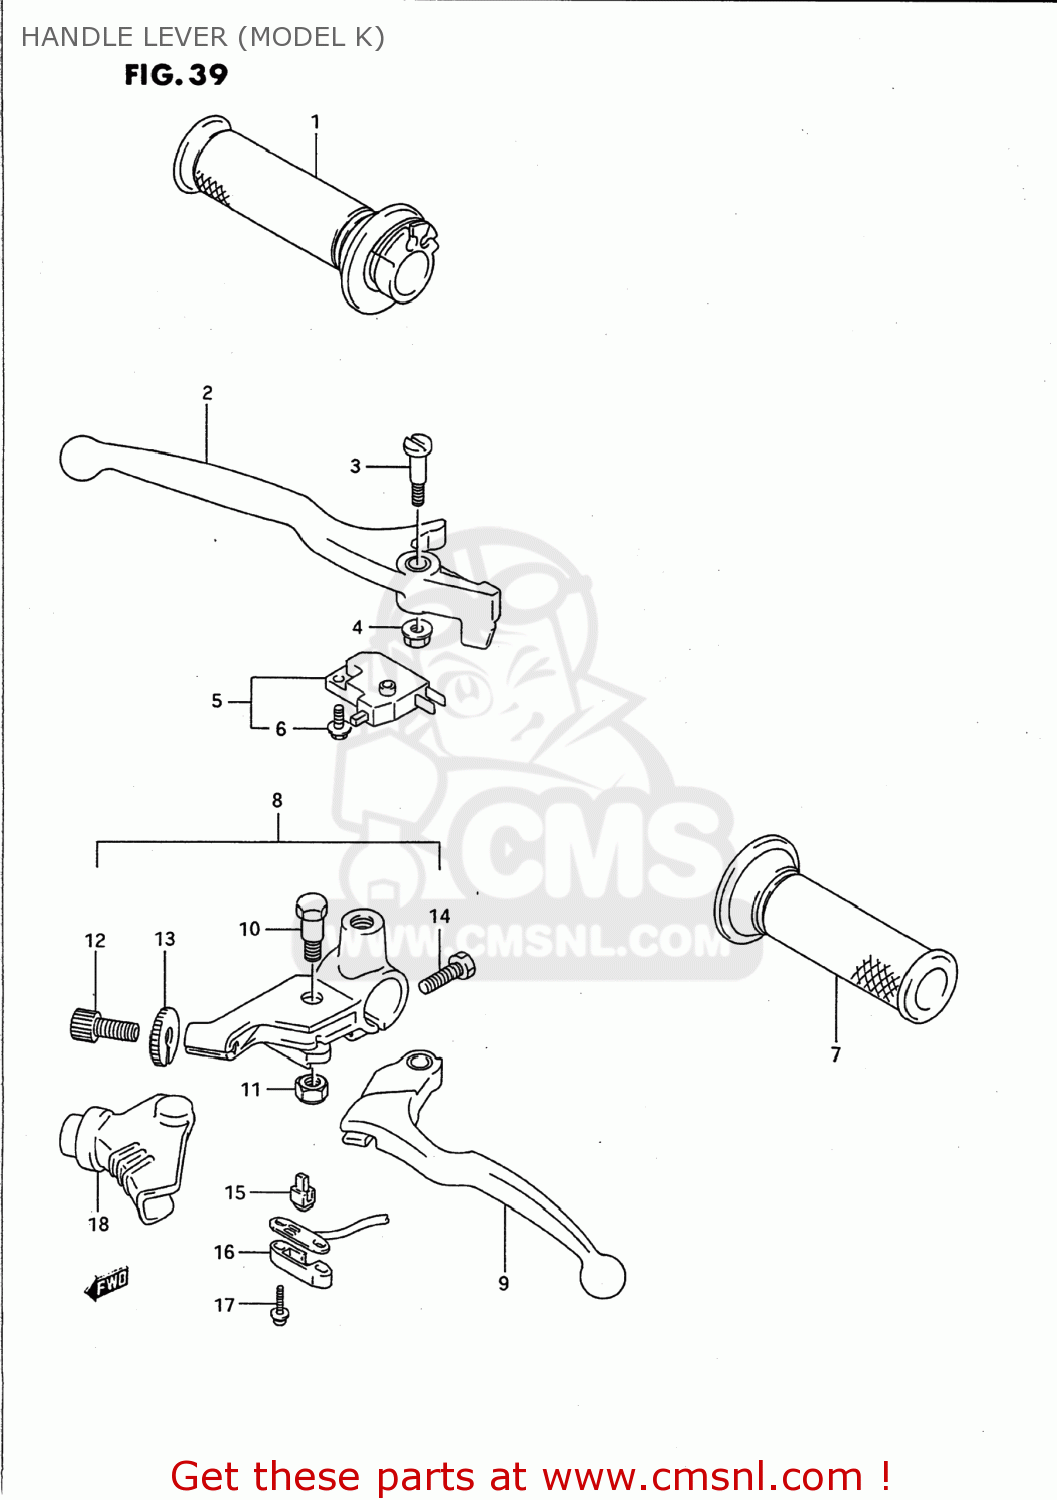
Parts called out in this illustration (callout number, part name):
1	GRIP,THROTTLE
2	LEVER,BRAKE
3	BOLT,LEVER PIVOT
4	NUT 6MM
5	SWITCH ASSEMBLY,STOP
6	SCREW
7	GRIP,L
8	CLUTCH LEVER & SWITCH ASSY
9	LEVER,CLUTCH
10	BOLT,LEVER
11	NUT
12	ADJUSTER,CABLE
13	NUT,CABLE ADJUSTER
14	BOLT
15	CONTACT,SWITCH
16	COVER,FR BK TERMINAL BASE
17	SCREW
18	COVER,CLUTCH LEVER
